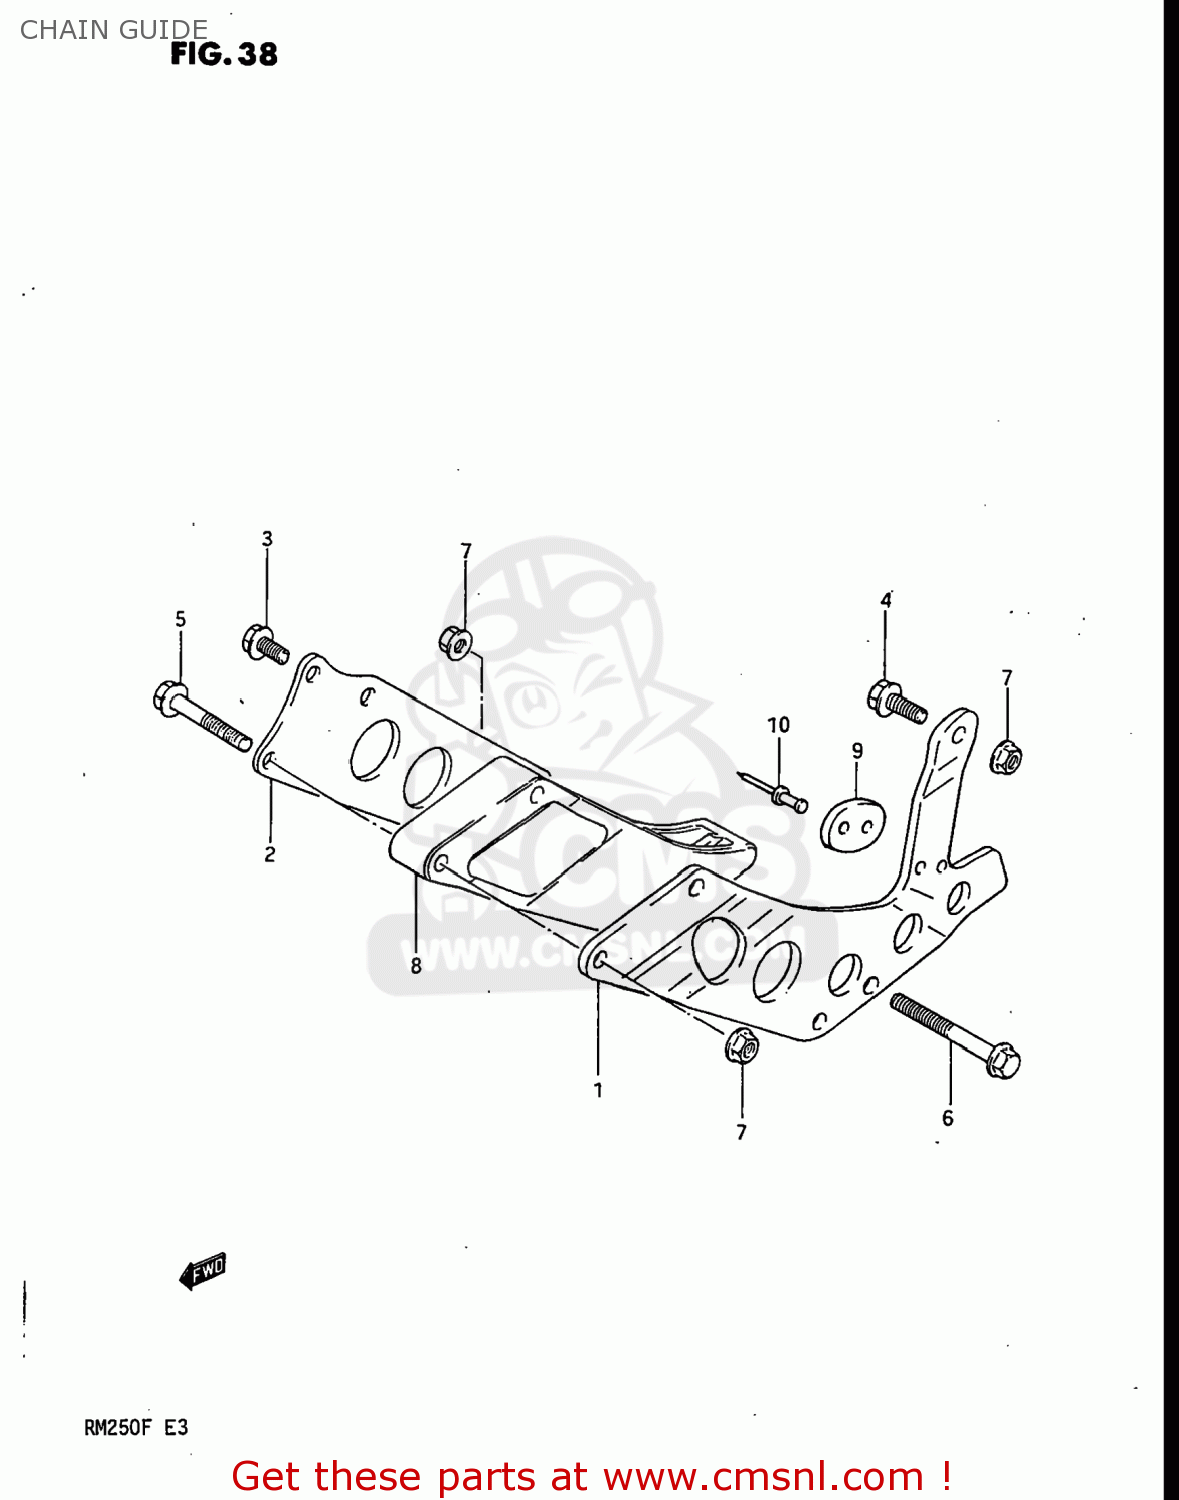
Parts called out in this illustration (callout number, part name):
1	PLATE,CHAIN GUIDE,OUTER
2	PLATE,CHAIN GUIDE,INNER
3	BOLT
4	BOLT,REAR
5	BOLT
6	BOLT,UNDER
7	NUT
8	DEFENSE,CHAIN GUIDE
9	PAD,GUIDE
10	RIVET
